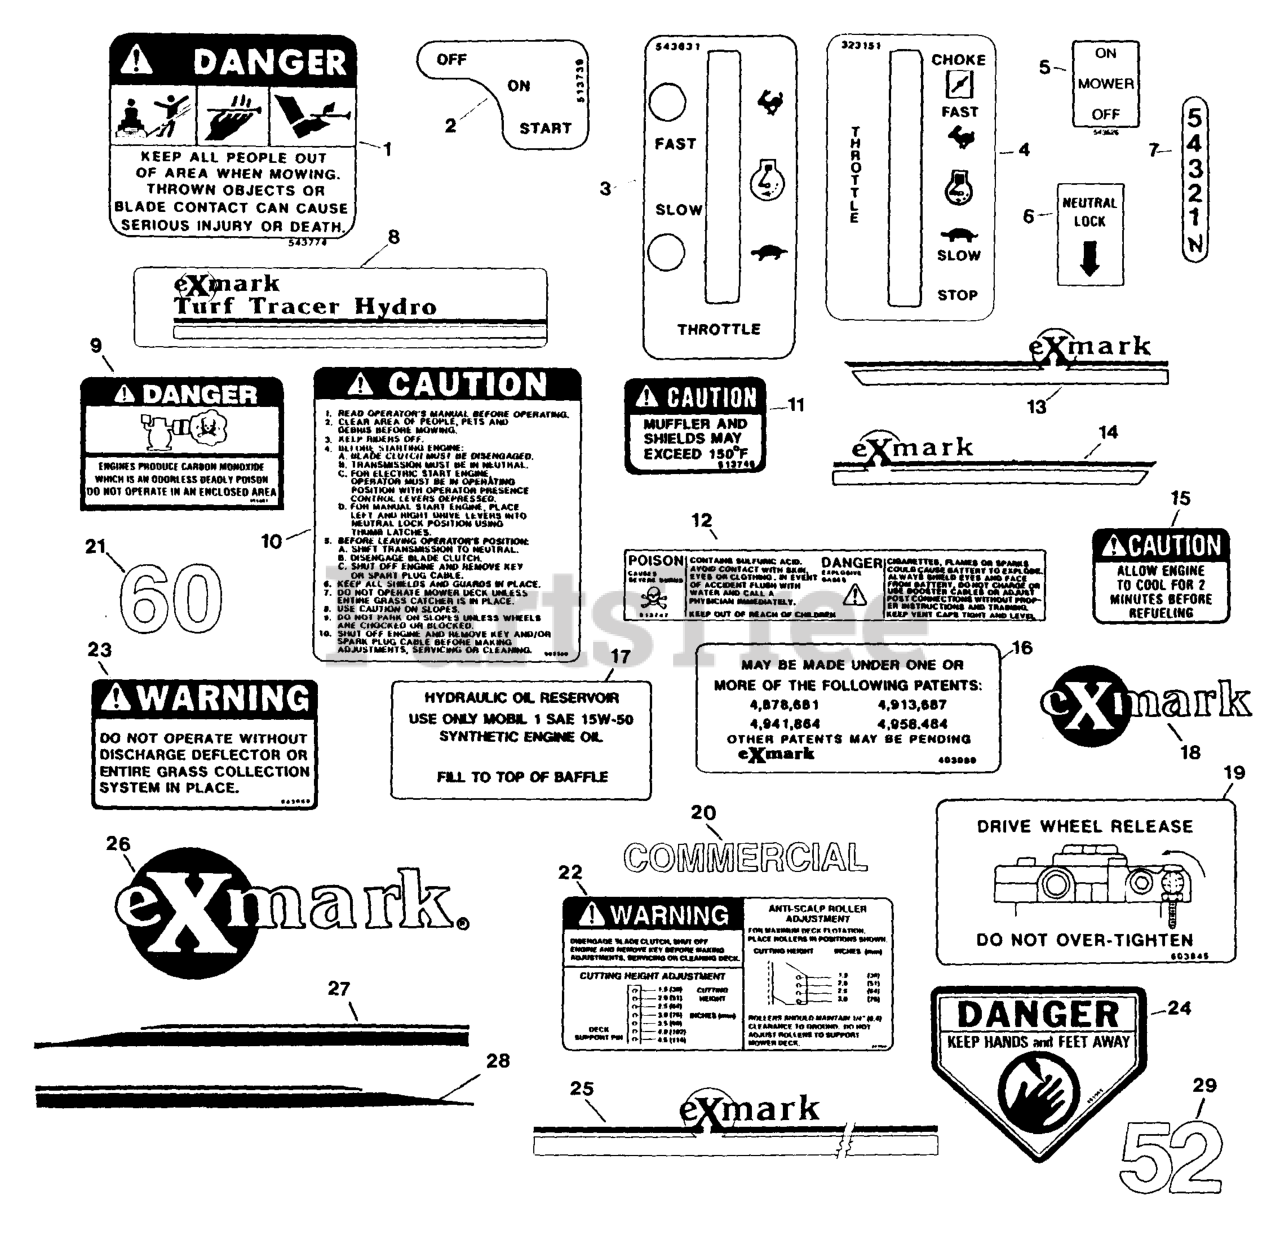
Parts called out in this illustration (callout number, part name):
1	DECAL-DANGER
5	DECAL-MOWER SWITCH
6	DECAL,NEUTRAL LOCK
7	DECAL - SHIFTER
12	DECAL-BATTERY
17	DECAL,HYD TANK
19	DECAL,DRIVE RELEASE
24	DECAL-DANGER
